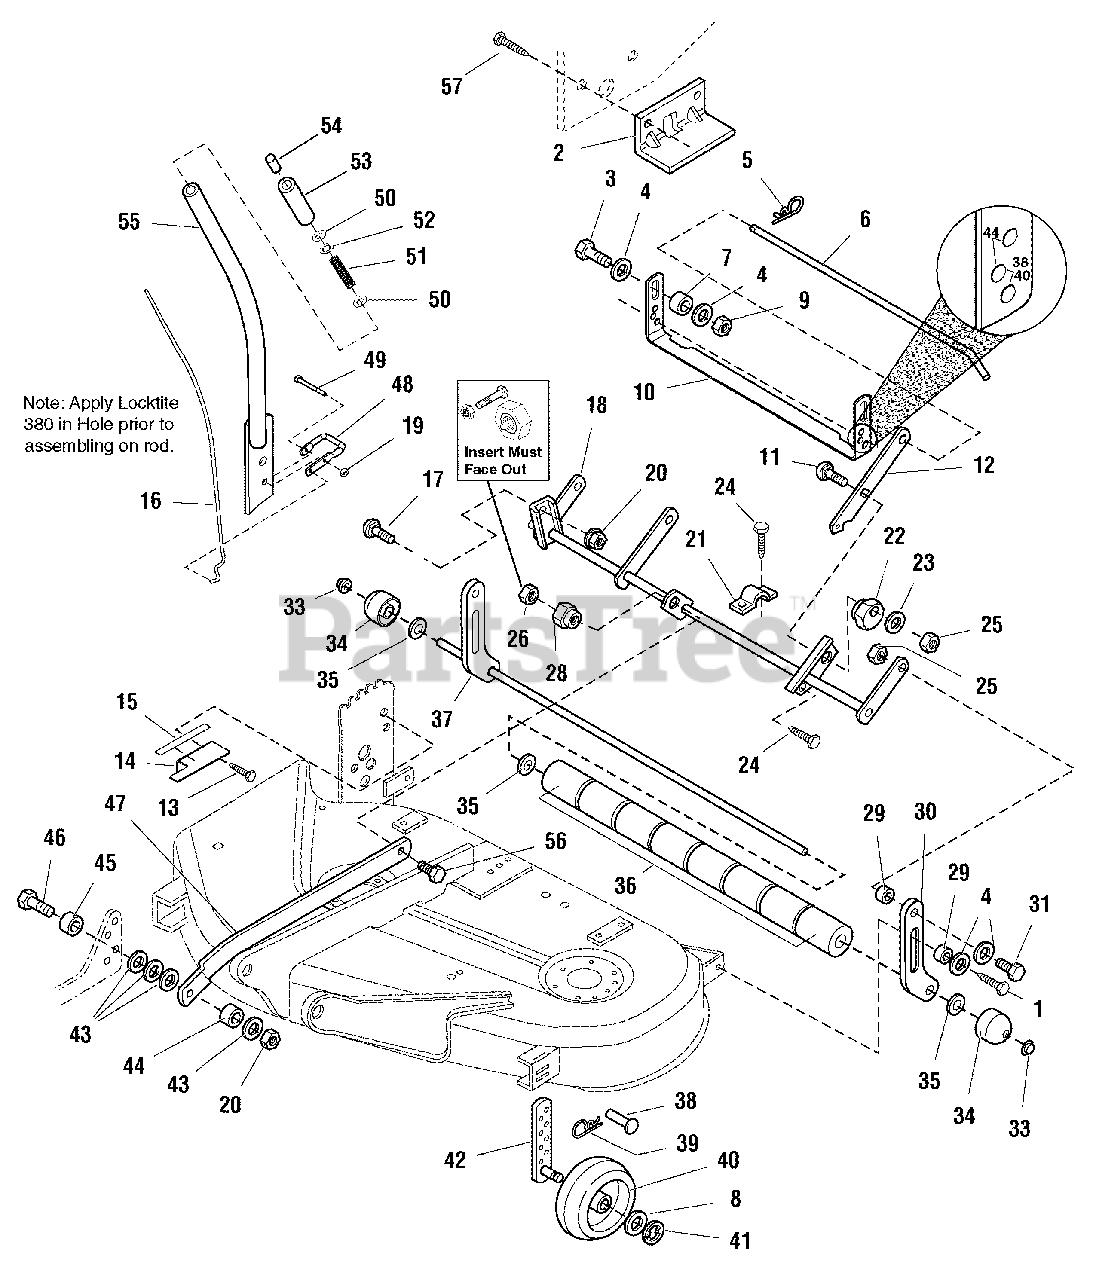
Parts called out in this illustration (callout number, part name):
1	CAPSCREW, Taptite Hex Washer Head, 5/16-18 x 1
2	BRACKET, Upstop
3	CAPSCREW, Hex Head, 5/16-18 x 1-1/4
4	WASHER, 5/16
5	CLIP, Spring
6	ROD, Transport
8	WASHER, 1/2
9	NUT, Hex Lock, 5/16-18
10	U-BRACKET
11	CARRIAGE BOLT, 5/16-18 x 1-1/4
13	CAPSCREW, Hex Head, Taptite, 5/16-18 x 1/2
14	BRACKET, Decal
15	DECAL, Height
17	CARRIAGE BOLT, 3/8-16 x 1
18	ROCKER ARM ASSEMBLY
19	NUT, Hex Lock, 1/4-20
20	NUT, HEx Lock ESNA, 3/8-16
21	STRAP
23	WASHER, Flat, 5/16
24	CAPSCREW, Taptite Hex Washer Head, 5/16-18 x 3/4
25	NUT, Hex, Flange Collar Lock, 5/16-18
26	NUT, Hex Lock, Aluminum Insert, 3/8-16
28	NUT, Hex Adjusting, .99 DIA .687
30	BAR, Roller, Support
31	CAPSCREW, Hex Head, 5/16-18 x 1
33	PUSHNUT, 5/8"
34	ROLLER, End
35	WASHER, 5/8
37	SHAFT ASSEMBLY
39	CLIP, Hair
40	GAUGE WHEEL
41	E-RING, 1/2
42	ARM ASSEMBLY, Adjustable
43	WASHER, Flat, 3/8
46	CAPSCREW, Hex Head, 3/8-16 x 2
49	CAPSCREW, Hex, 1/4-20 x 2-1/4
50	WASHER
51	SPRING, Compression
52	PUSH NUT, 1/4
55	HANDLE ASSEMBLY
56	CARRIAGE BOLT, 3/8-16 x 1-1/2
57	CAPSCREW, Taptite Hex Washer Head, 5/16-18 x 5/8
